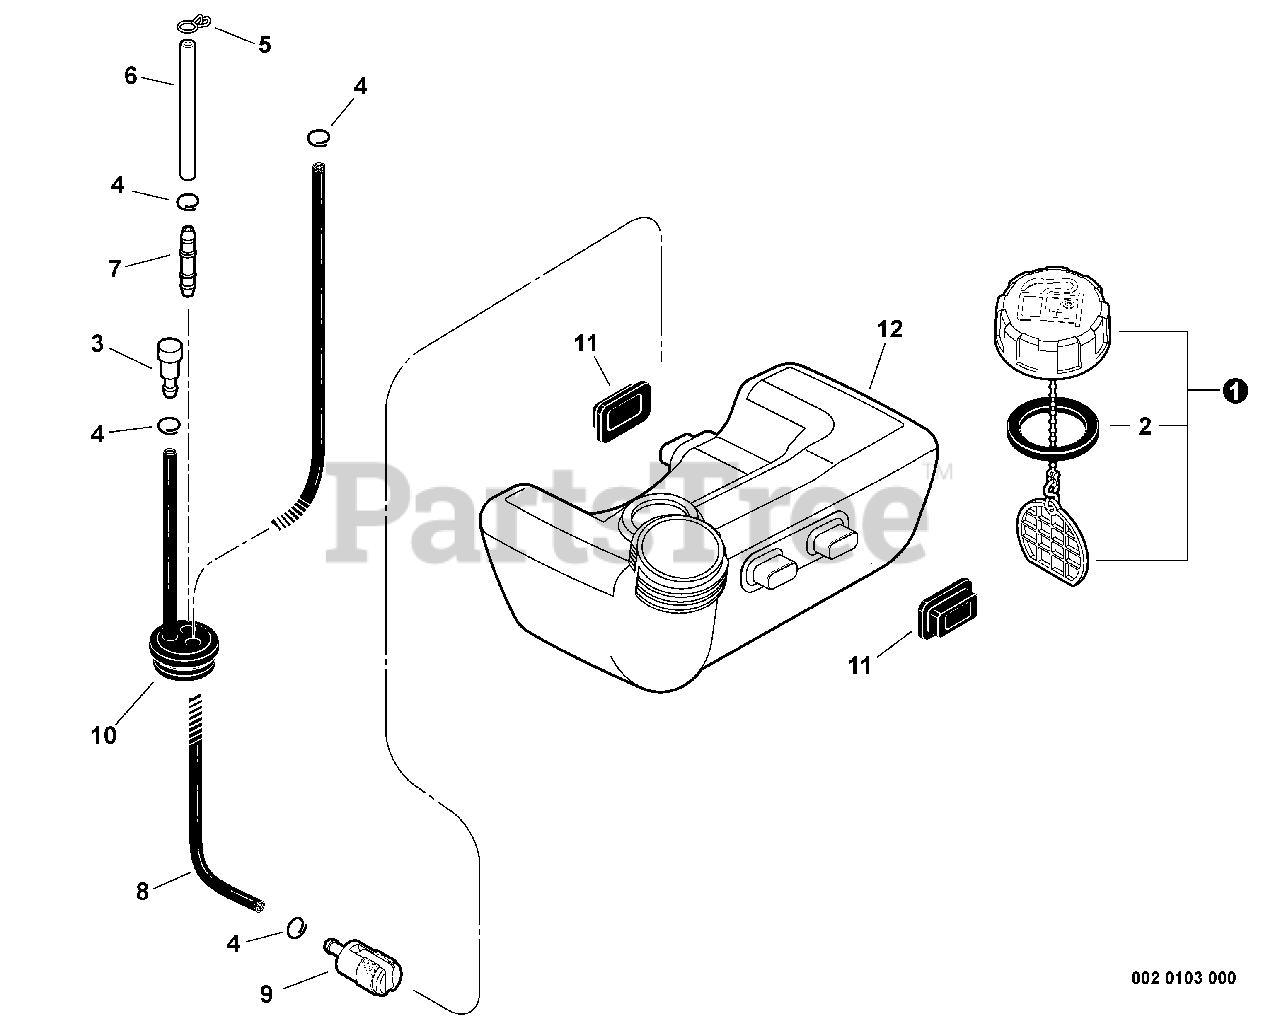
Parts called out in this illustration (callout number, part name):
1	CAP ASSY, FUEL
2	GASKET, FUEL CAP
3	VENT ASSY
4	CLIP Ø6
5	CLIP, SPRING Ø5.2
6	PIPE, FUEL RETURN L= 52.5 MM
7	CONNECTOR, PIPE
8	PIPE, FUEL 3.3×6×160
9	FILTER, FUEL 125-528
10	GROMMET, FUEL W/VENT PIPE
11	CUSHION, FUEL TANK
12	TANK, FUEL
